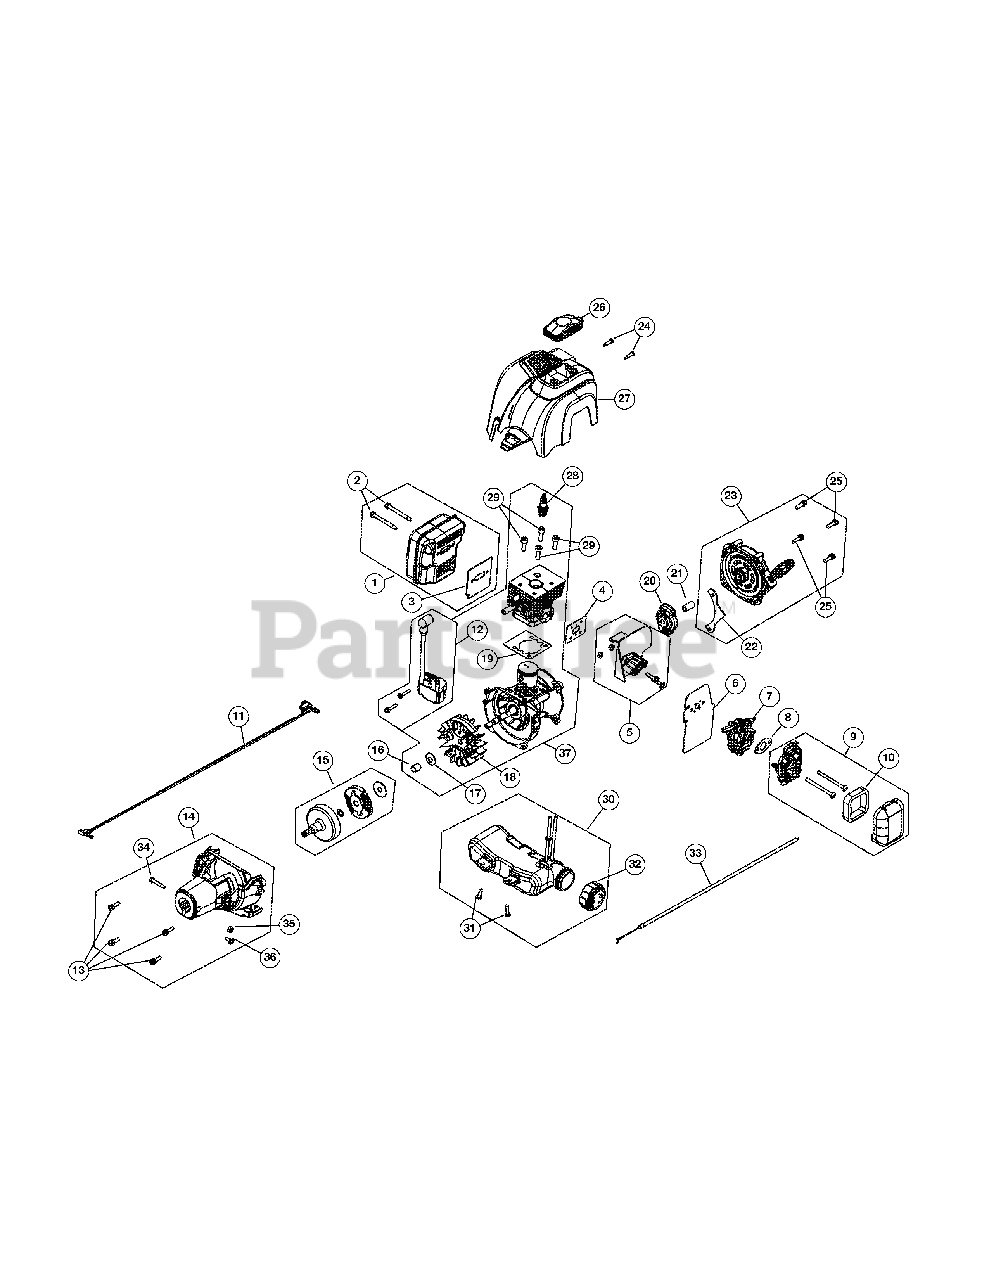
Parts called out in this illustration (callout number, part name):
1	Muffler Assembly
2	Mufler Bolts
3	Muffler Gasket
4	Gasket
5	Insulator Assembly (includes 4)
6	Heat Shield
7	Carburetor
8	Carburetor Gasket
9	Aircleaner Assembly (includes 10)
10	Aircleaner Filter
11	Lead Wire
12	Module Assembly
13	Clutch Cover Screws
14	Clutch Cover Assembly (includes 13, 34-36)
15	Clutch Assembly
16	Spacer
17	Washer
18	Flywheel Assembly
19	Cylinder Gasket
20	Pawl Assembly
21	Electric Starter Adapter
22	Starter Cover Guard (includes 25)
23	Starter Assembly (includes 22 & 25)
26	Spark Plug Cover
27	Engine Cover
28	Spark Plug
29	Cylinder Screws
30	Fuel Tank Assembly (includes 31 & 32)
31	Fuel Tank Screws
32	Fuel Cap
33	Throttle Cable
34	Screw
36	Anti-Rotation Screw
37	Shortblock (includes 12, 16-19 & 28-29)
